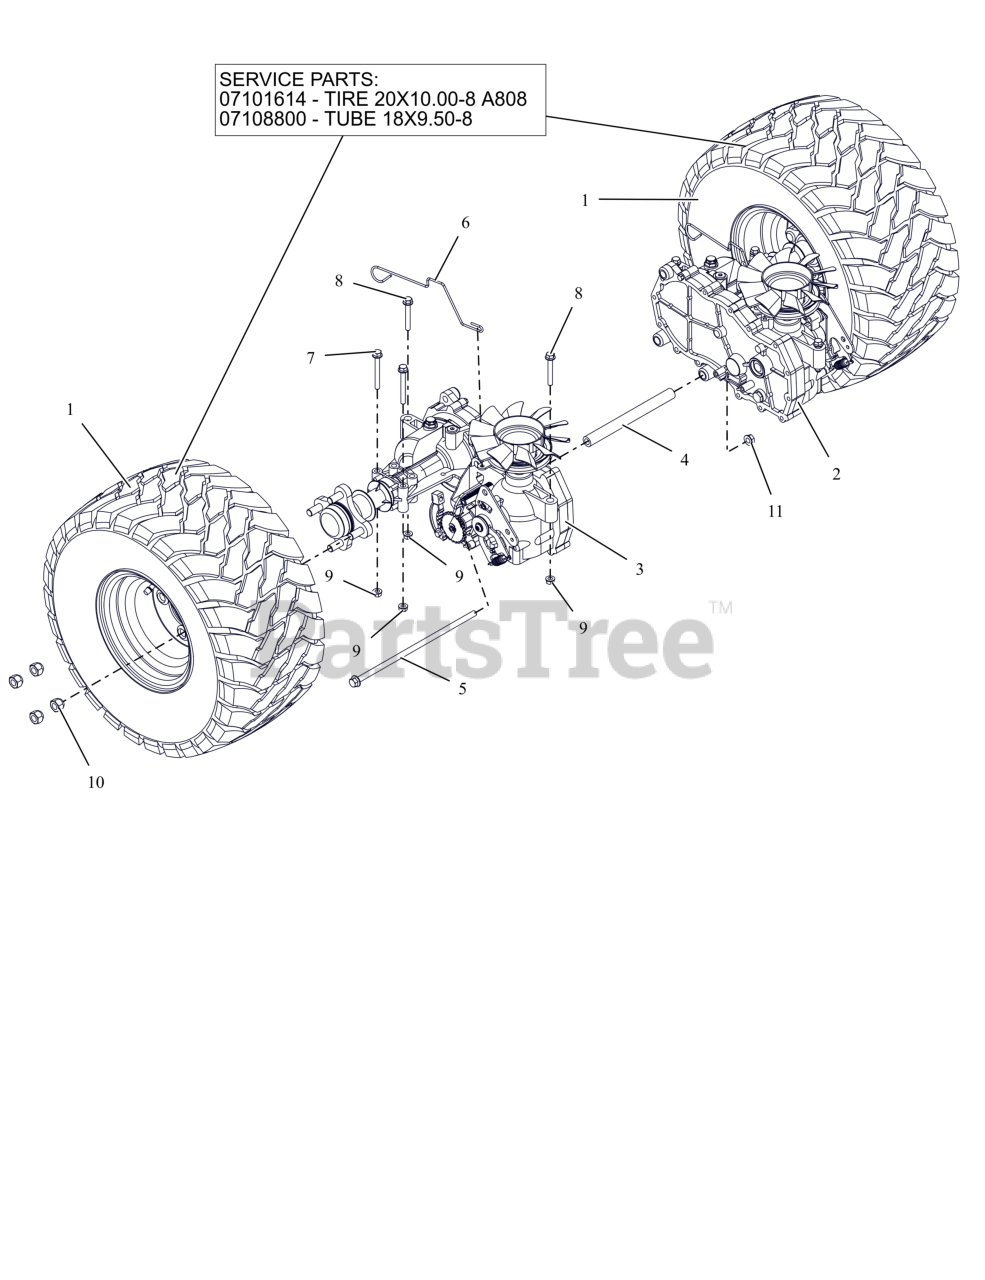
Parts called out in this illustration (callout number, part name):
1	ASM-WHL/TIRE 20X10.00-10 K505
1	TIRE 20X10.00-8 A808 TREAD
1	VALVE STEM ASS'Y
1	TUBE 18X6.50/8.50/9.50-8/20X8.00/10.00-8
2	TRANSAXLE- SERVICEABLE EZT -LH
3	TRANSAXLE- SERVICEABLE EZT -RH
4	SPCR, TRANSAXLE .438 ID X .750 OD X 8.18 (BLACK)
5	BLT, HEX-FLG 0.375-16X11.5 GR5 ZC120
6	WIRE- DUMP VALVE LEVER
7	BLT,HEX-FLG .31-18X2.75 G5 ZCC
8	BLT,HEX-FLG .31-18X2.25 G5 ZCC
9	NUT,LK-CTR-FLG .31-18 GF ZCC
10	NUT, WHEEL .50-20 ZCC
11	NUT-LK-CTR-FLG .375-16 GF ZCC
